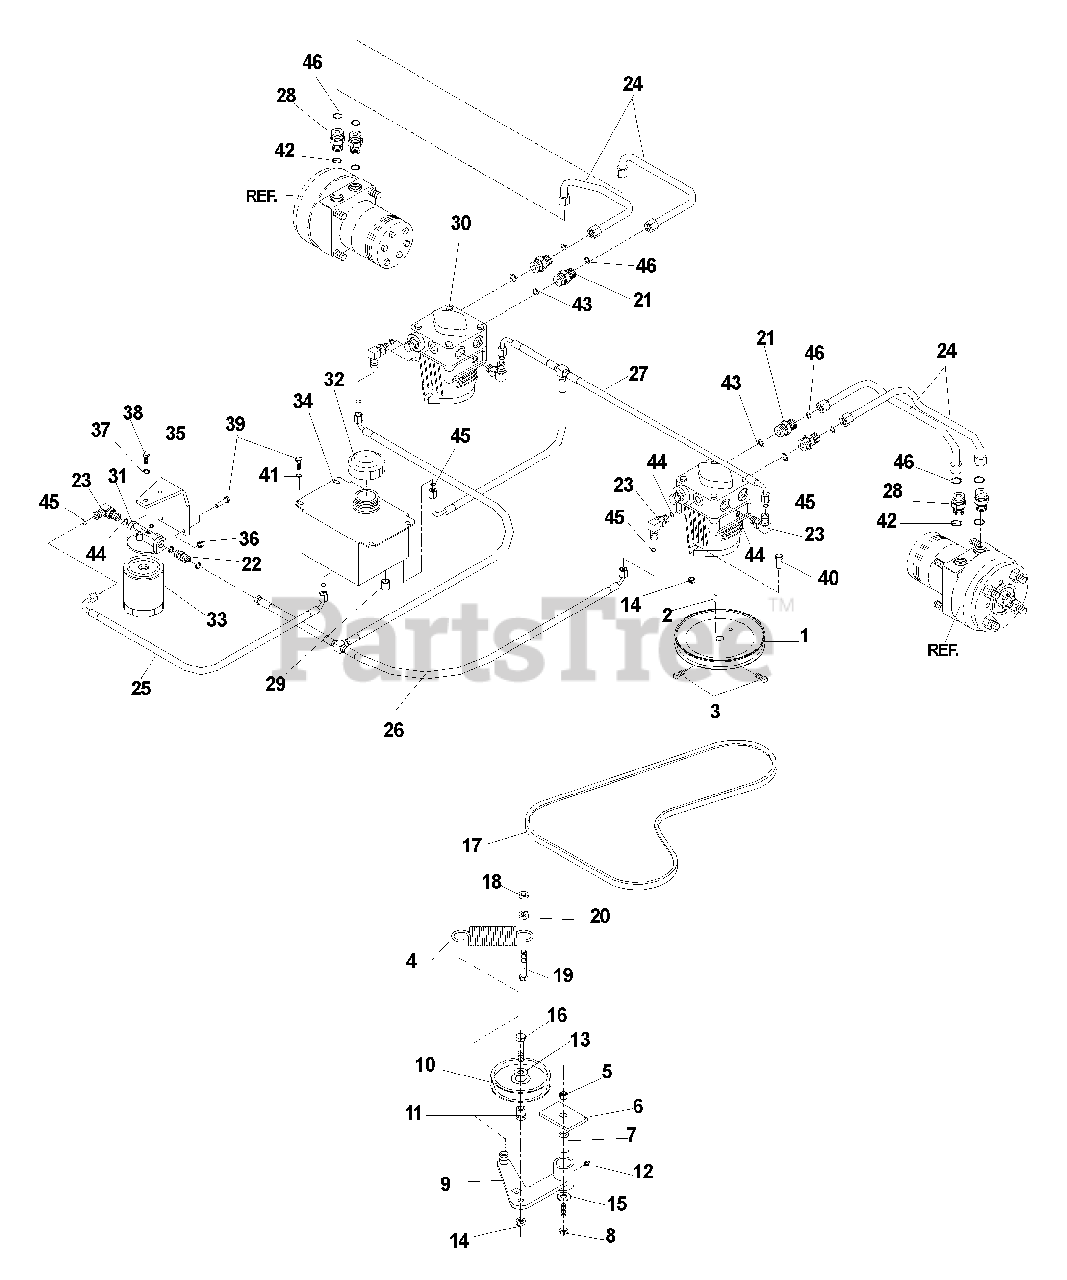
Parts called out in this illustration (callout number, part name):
2	KEY, 5MM SQ X 30MM
3	SCREW, 5/16-18 X 5/8, SET
4	SPRING, EXTENSION
5	NUT, 1/2-13, NYLOC
7	BUSHING, PIVOT
8	HCS, 1/2-13 X 3 1/4, GR5
9	IDLER ARM
10	PULLEY, IDLER
11	BUSHING, FLANGE IDLER
12	ZERK, STRAIGHT, 1/4-28
13	WASHER, 3/8
14	NUT, 3/8-16, CENTERLOCK
15	WASHER, 9/16
16	HCS, 3/8-16 X 1 3/4, GR5
17	PUMP BELT
18	NUT, 3/8-16, NYLOC
19	HCS, 3/8-16 X 2, GR5
20	NUT, 3/8-16, WHIZLK
21	FITTING, F6400-8-8-0
22	HYDRAULIC FITTING
23	FITTING, F6801-6-6-0
24	HYDRAULIC LINE
26	"T" ASSEMBLY
27	"T" ASSEMBLY
28	STRAIGHT FITTING
30	10CC PUMP W/RTN'S
31	FILTER HEAD
32	CAP-HYDRO RESERVIOR
33	FILTER ELEMENT
35	OIL FILTER BRACKET
36	NUT, 1/4-20, NYLOC
37	LOCKWASHER, 1/4
38	HCS, 1/4-20 X 5/8, GR5
39	HCS, 1/4-20 X 3/4, GR5
40	HCS, 3/8-16 X 1, GR5, WHIZLK
41	WASHER, 1/4
42	"O" RING, 3/4
43	"O" RING, 1/2
44	"O" RING, 3/8
45	"O" RING FLARE, 3/8
46	"O" RING FLARE, 1/2
